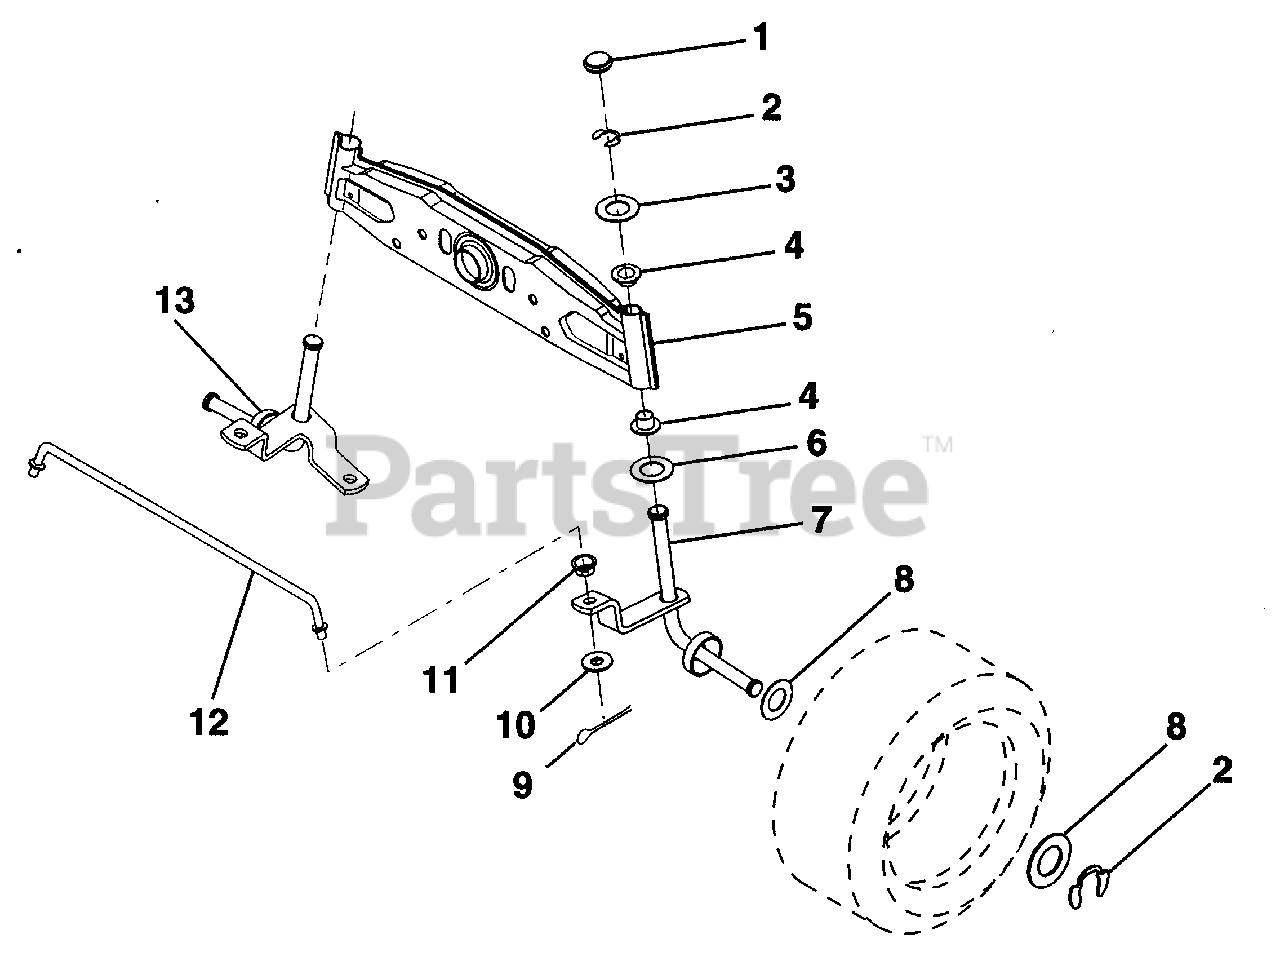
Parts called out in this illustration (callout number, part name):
1	Cap, Spindle (AYP part number)
2	Ring, Klip (AYP part number)
3	Washer 25/32 x 1-5/8 x 16 Gauge (AYP part number)
4	Nyliner (AYP part number)
5	Axle, Front (AYP part number)
6	Bearing, Thrust (AYP part number)
7	Spindle Assembly, RH (AYP part number)
8	Washer 25/32 x 1-1/4 x 16 Gauge (AYP part number)
9	Pin, Cotter 1/8 x 3/4 (AYP part number)
10	Washer 13/32 x 13/16 x 16 Gauge (AYP part number)
11	Bushing (AYP part number)
12	Rod, Tie (AYP part number)
13	Spindle Assembly, LH (AYP part number)
